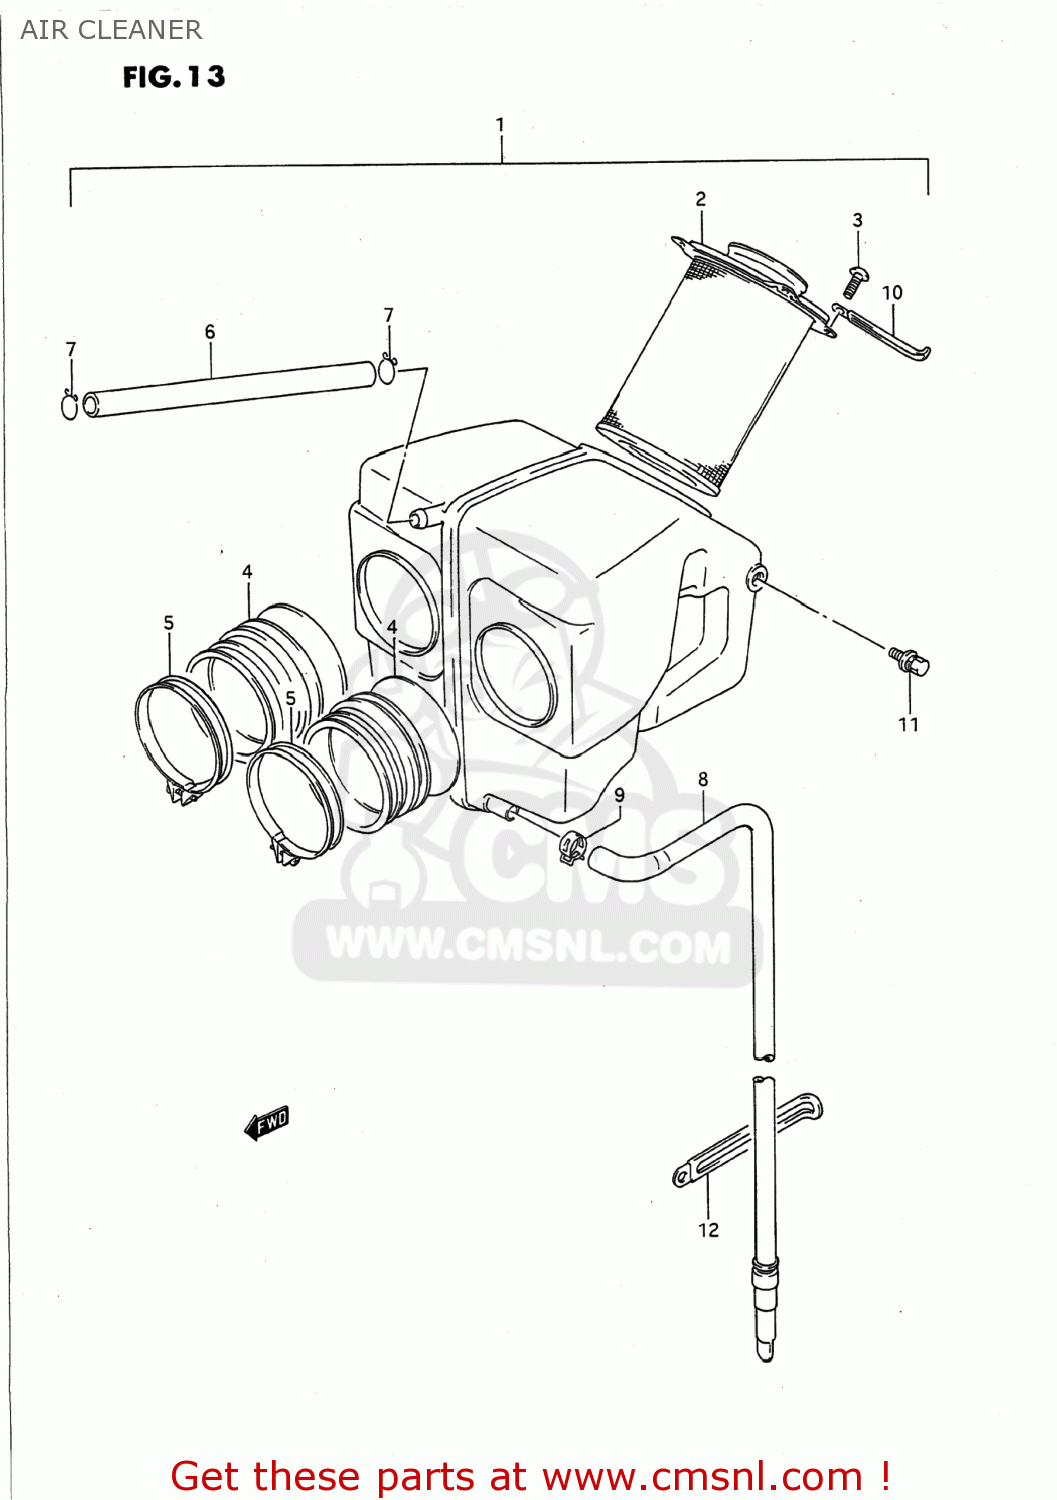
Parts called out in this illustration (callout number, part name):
1	CLEANER ASSEMBLY,AIR
2	FILTER ASSY
3	SCREW
4	TUBE,OUTLET
5	CLAMP
6	TUBE,BREATHER
7	CLIP
8	DRAIN TUBE
9	CLIP
10	CLAMP
11	VIS
12	CLAMP
